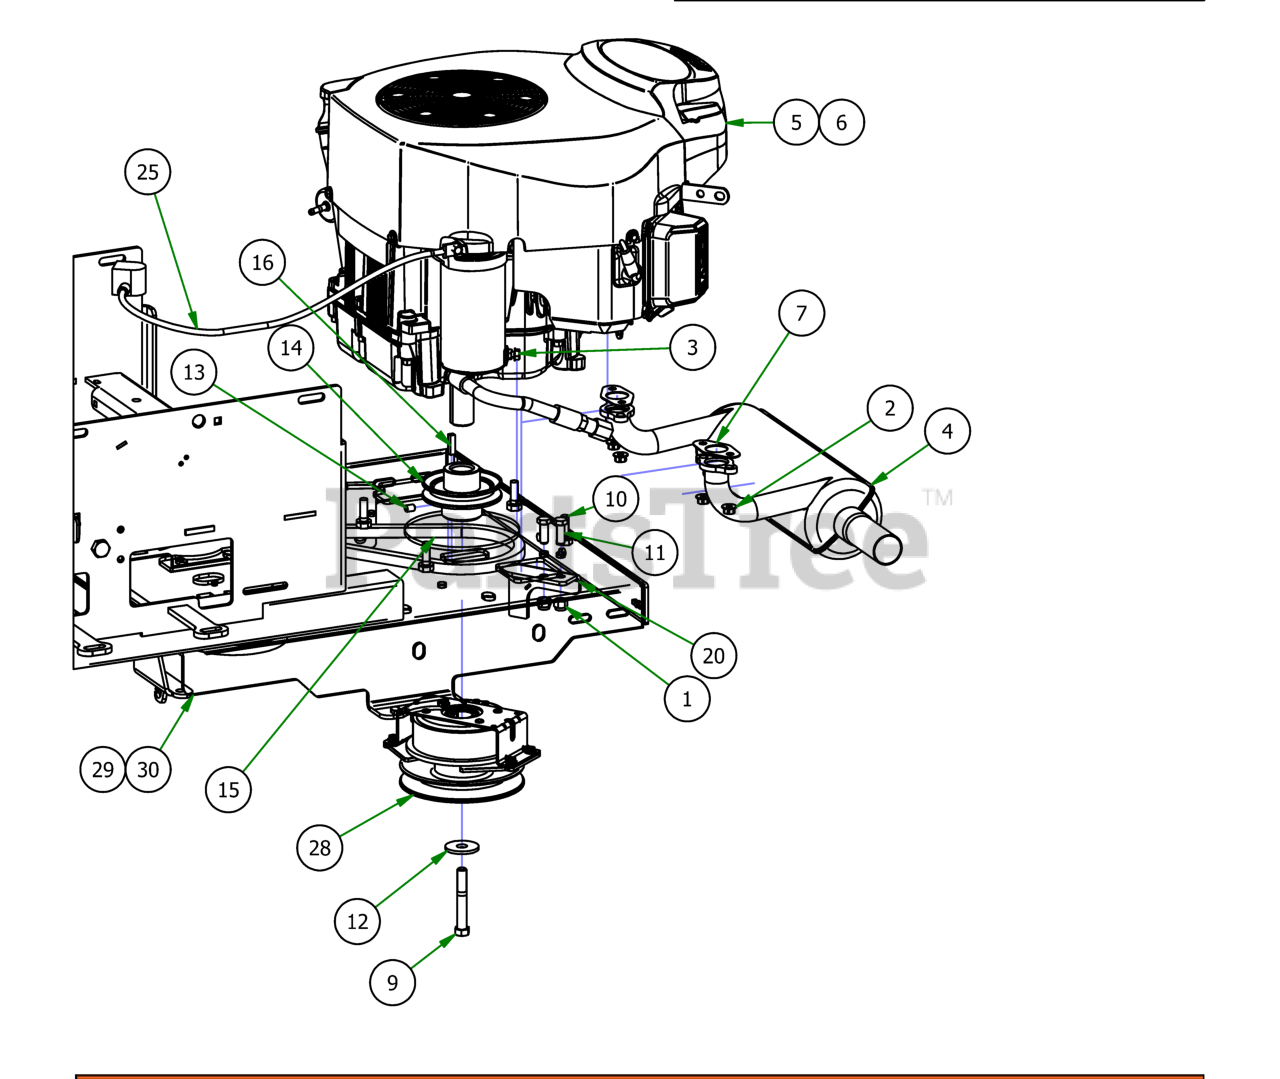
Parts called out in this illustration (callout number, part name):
1	3/8 Nylock Nut
2	M8 Flange Nut for Kohler Exhaust
3	1/4-20 Hex Flange Nuts Zinc w/Serrations
4	Kohler Muffler
5	Kohler MZ Magnum 740cc
6	Kohler KT-725
7	Exhaust Gasket
8	Spark Plug
9	7/16"-20 x 3" Hex Bolt Gr. 8
10	3/8 x 1 1/8 bolt
11	3/8" x 1" Hex Bolt
12	Clutch Washer
13	3/8" Set Screw
14	3-3/4" Motor Pulley
16	1/4" x 1" Key
17	37" Fuel Line Assembly
18	Oil drain Hose
20	2017 MZ Clutch Stop
21	KT-725 & KT-740 Precleaner
22	KT-725 & KT-740 Air Element
23	KT-725 & KT-740 Oil Filter
24	Universal Fuel Filter
25	Ground Cable
26	12" Red Battery Cable
27	MZ Kohler EPA Canister Assembly
29	2017 MZ/ZT 54"-62" Frame
30	2017 MZ/ZT 42"-48" Frame
31	2017 MZ Magnum Control Panel
32	2017 MZ Control Panel Assembly
